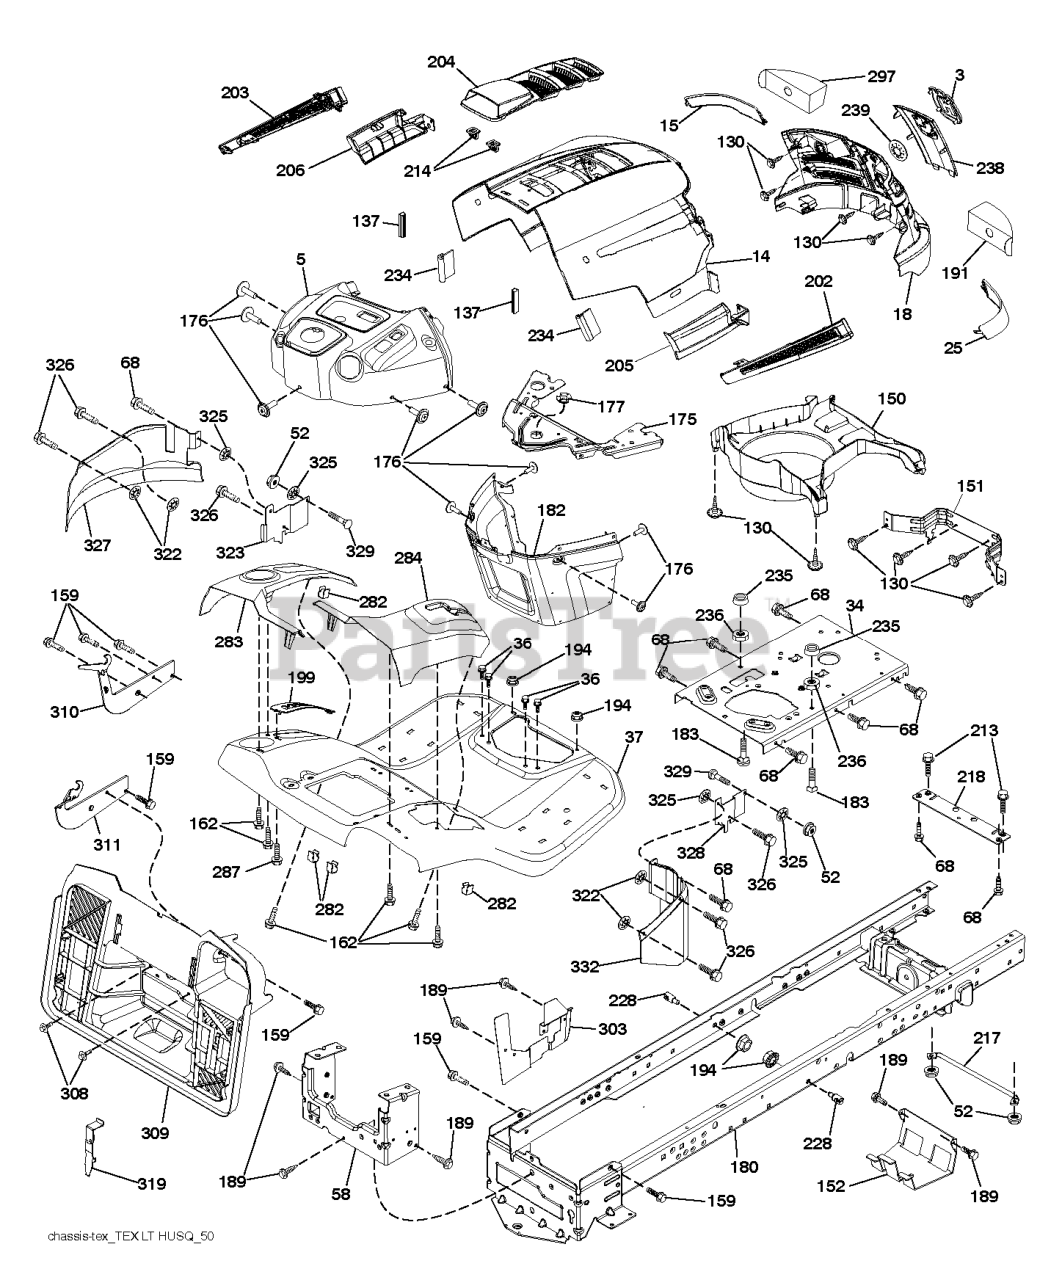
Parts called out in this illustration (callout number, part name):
3	RP LOGO
5	DASH
14	HOOD
15	LENS.HUSQVARNA LT.LH
18	GRILLE.SVC.HUSQVARNA.LT.GREY
25	LENS.HUSQVARNA LT.RH
34	PLATE.ENGINE.WELDED.CHASSIS
36	SCREW 5/16"
52	NUT.71038.31-18.HEX.NYLOCK
58	DRAWBAR UPPER 2PC SMALL FENDER
68	Screw 5/16-18 x 1/2 Hex, Self Tapping 5/16-18 x 1/2
130	SCREW.#10 X 0.750.BOS
137	BUMPER DASH
151	BRACKET PIVOT
152	SHIELD.BROWNING.W/TEX
159	SCREW, 3/8-16X3/4
162	SCREW.HI-LO.CONSOLE
175	CROSSMEMBER
176	SCREW.#10-24X5/8.RN.QU
177	BUSHING STEERING
180	CHASSIS.WLDMNT.14GA.2PC.18".TI
182	DASH.LOWER.PREDATOR LT
183	BOLT.5/16-18X1-1/4 FULL THD
189	SCREW
191	INSERT.REFLECTIVE.RH.
194	NUT LOCK HEX FLANGE 5/16-18
199	PLATE DECK LIFT
202	VENT SIDE HOOD LH
203	VENT SIDE HOOD RH
204	VENT TOP HOOD
205	SKIRT SIDE RH
206	SKIRT SIDE LH
213	BOLT
214	CLIP.RETAINER.TINNER.
217	ROD.PIVOT.HOOD
218	X-PIECE.HOOD.STOP.NON/
228	STUD.FASTNER.W/ANTI-ROTATE
234	BUMPER.HOOD.TEX.HUSQVARNA
235	SPACER FENDER
236	NUT.CENTERLOCK.5/16-
238	TRIM
282	CLIP.RETAINER.CONSOLE.LT.HUSQ
283	CONSOLE.DCKLFT.SRD.BGR
284	CONSOLE.SHFT.SRD.RH.GR
287	SCREW 1/4X20
297	INSERT REFLECTIVE
303	SHIELD CHASSIS LEFT
308	BOLT.5/16-18UNCX3/4 W/SEMS.BLK
309	BACKPLATE.BAGGER.V2.SRD
310	Bracket Hangar Bag LH
311	Bracket Hangar Bag RH
319	BRACKET.ACTUATOR.BAGGER.SRD
322	PALNUT 1/4
323	GUARD FRONT LEFT
325	WASHER 5/16"
326	SCREW 14-20 X 5/8
327	GUARD LEFT
328	GUARD FRONT RIGHT
329	BOLT
332	GUARD RIGHT
